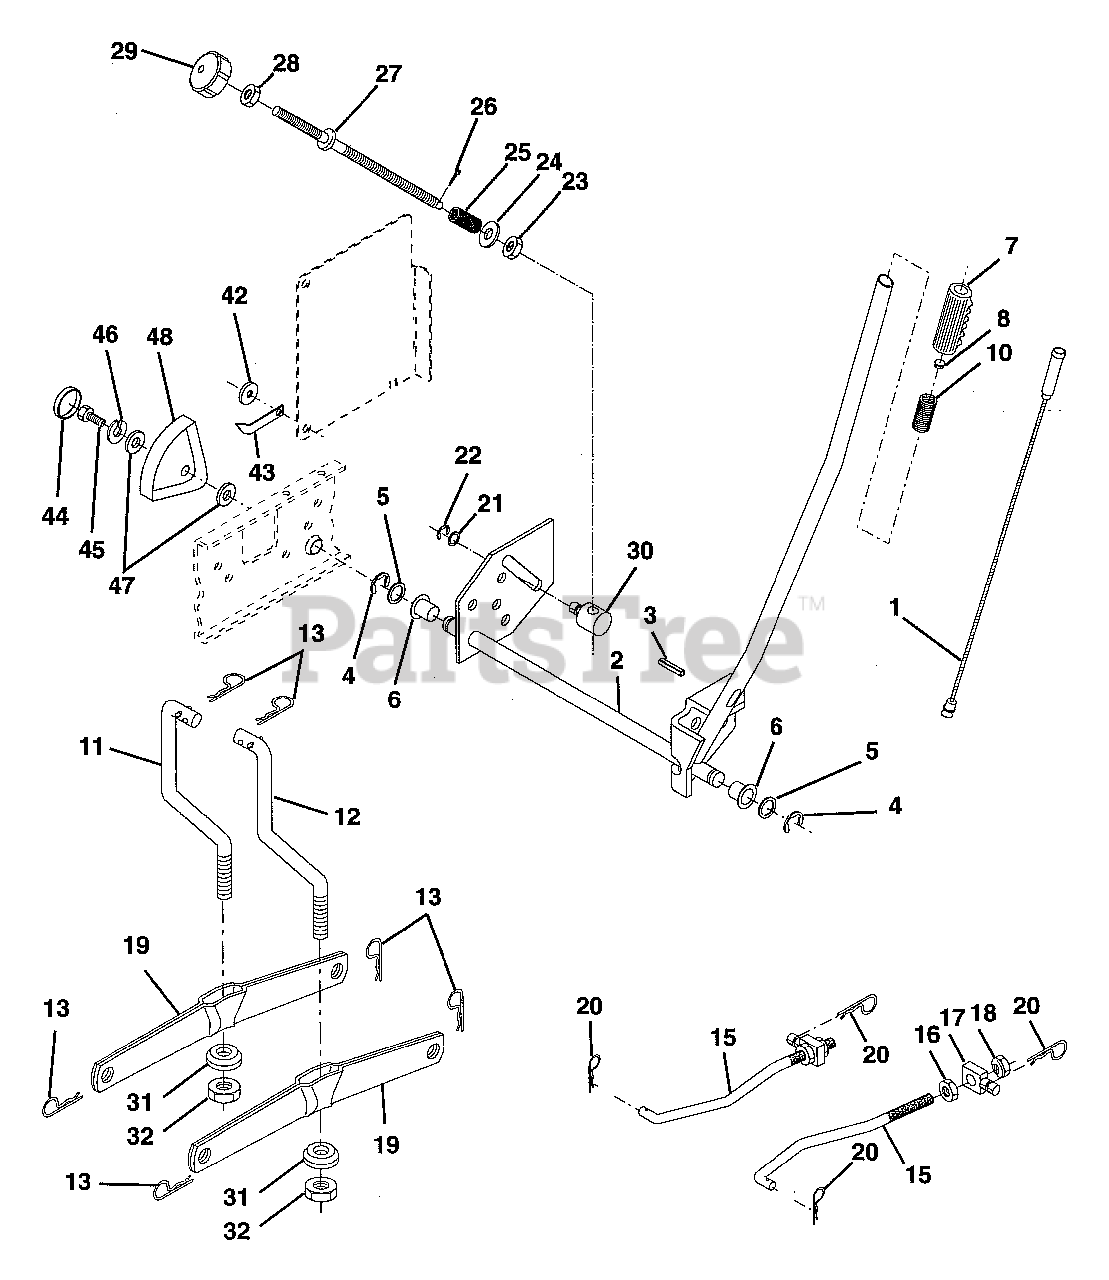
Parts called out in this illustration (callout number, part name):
1	Wire Asm Inner W/plunger 20 56
2	Shaft Asm Lift RH w/lnf
3	Pin Groove 1 500 Zinc
4	E Ring #5133-62
5	Washer 21/32 X 7/8 X 16 Ga
6	Bearing Nylon Blk 629 Id
7	Grip Handle Fluted Blk
8	Button Plunger Black
10	Spring Cprsn 3 750 Oiled
11	Link Lift LH
12	Link Lift RH
13	Retainer Spring
15	Link Front
16	Nut Jam Hex 1/2-13 Unc
17	Trunnion Blk Zinc
18	Nut Lock W/wsh 1/2-13unc
19	Arm Suspension Rear
20	Retainer Spring
21	Washer 15/32 X 3/4 X 16 Ga
22	Ring Klip #t5304-37
23	Nut Special
24	Washer 13/32 X 5/8 X 16 Ga
25	Spring 2-1/8"
26	Pin Cotter 3/32 X 1/2
27	Rod Adj Lift Zinc 9 00 Wrk Lg
28	Nut Hex Jam 3/8-16 Unc
29	Knob Inf 3/8-16 Unc Blk W/sym
30	Trunnion Dp Stop Dbl Thds PLT
31	Bearing Pvt Lift Spherical
32	Nut Lock 3/8-24 w/Nylon Insert
42	Washer Nylon .44 x .75 x .032
43	Pointer Height Indicator
44	Plug Hole Blk 1.485/1.515
45	Bolt Fin Hex 5/16-18 unc x 1
46	Washer Lock Hvy Hlcl Spr 5/16
47	Washer 11/32 x 1-1/2 x 10 Ga.
48	Scale Ind. Height Blk
